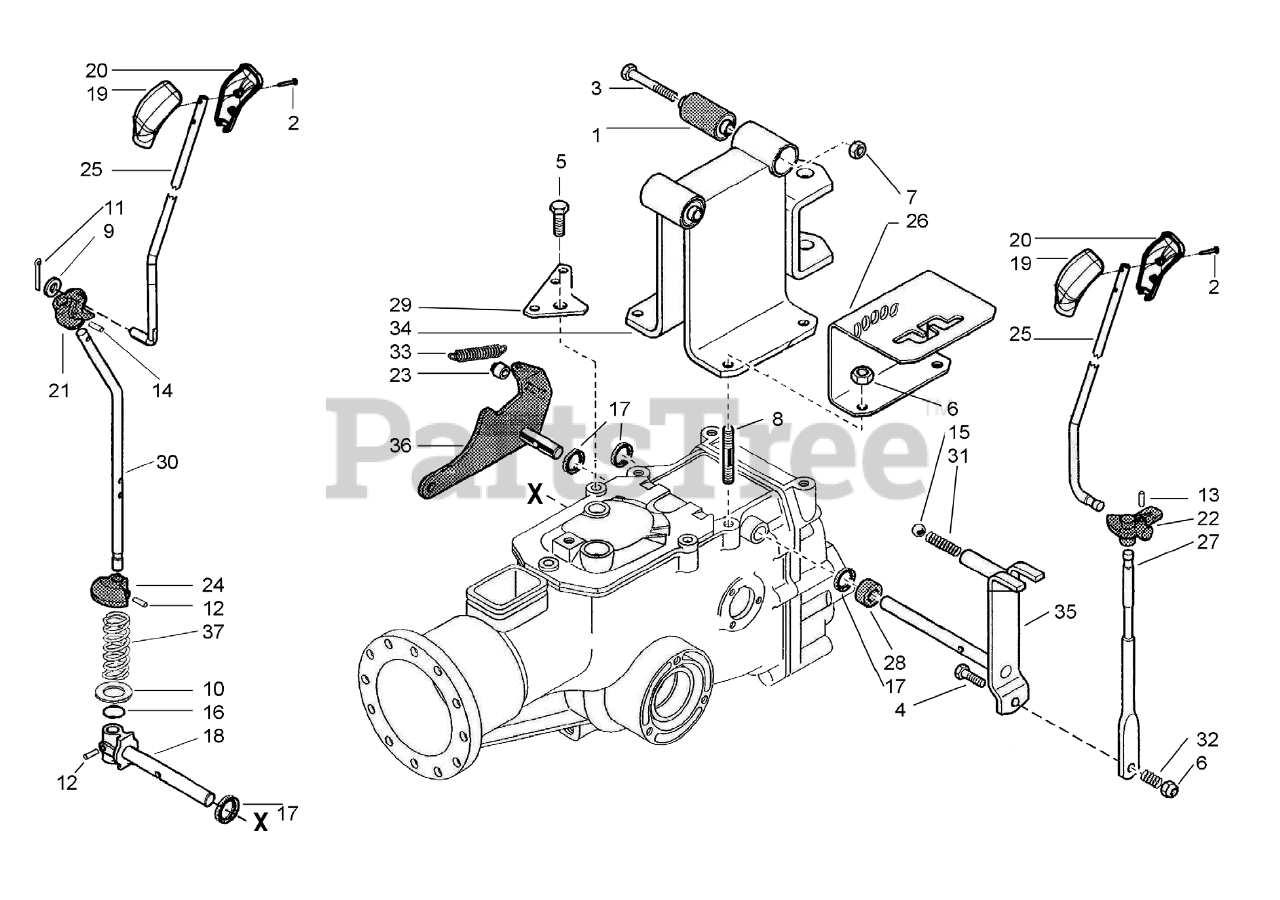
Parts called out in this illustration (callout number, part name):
1	SILENT BLOCK
2	SCREW
3	CAP SCREW, M10X75
4	CAP SCREW, M8X30
5	SCREW
6	LOCK NUT, M8
7	LOCK NUT, M10
8	STUD, M8X35X14X20
9	WASHER, FLAT M10.5X8
10	WASHER, FLAT M13
11	PIN, COTTER A 2X15
12	PIN, SPLIT 4X20 SPIROL
13	PIN, SPLIT 3X22 SPIROL
14	PIN, SPLIT 4X24 SPIROL
15	BALL 15/32
16	O-RING
17	OIL SEAL M14X22X4
18	PTO SHAFT
19	UPPER HDLE.REL.KNOB BLACK
20	LOWER HDLE.REL. KNOB BLACK
21	PTO ARTICULATOR
22	SPEED ARTICULATOR
23	PIN, PTO LOCKOUT
24	PTO LOCKOUT
25	CONTROL ROD
26	GEAR SELECTOR 3+2
27	LEVER, SPEED CONTROL
28	SPACER
29	REVERSE BRACKET
30	SHIFT ARM, PTO
31	SPRING
32	SPRING
33	SPRING
34	SUPPORT, HANDLEBAR
35	GEAR LEVER 3+2
36	LEVER, PTO LOCKOUT
